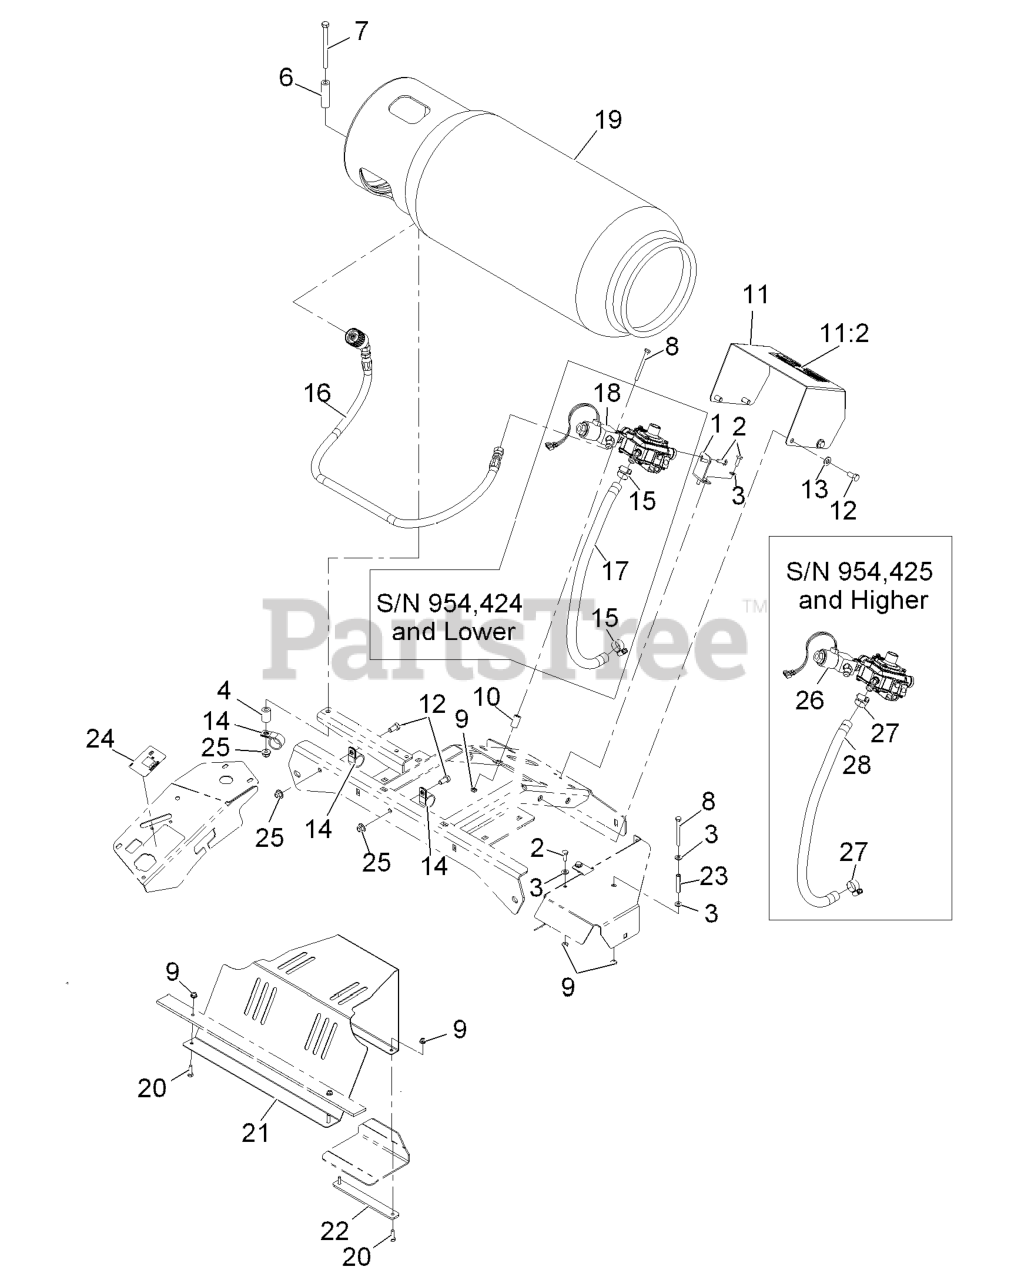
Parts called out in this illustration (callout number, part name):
1	BRACKET-REGULATOR
2	SCREW-HH
3	WASHER-FLAT
4	SPACER-HYDRO CONTROL, LH
6	SPACER-ANCHOR, CLUTCH
7	SCREW-HH
8	SCREW-HH
11	COVER ASM
11:2	DECAL-TANK REPLACEMENT
12	SCREW-HH
13	WASHER-FLAT
14	CLIP-LOOM
15	CLAMP-HOSE
16	LPG FUEL HOSE ASM
17	HOSE-LP
18	LP SOLENOID REGULATOR AS
20	SCREW-HH
21	SHEILD-FAN
23	SPACER-SPLIT
24	DECAL-METER, HOUR
25	NUT-HF, NI
27	CLAMP-HOSE
